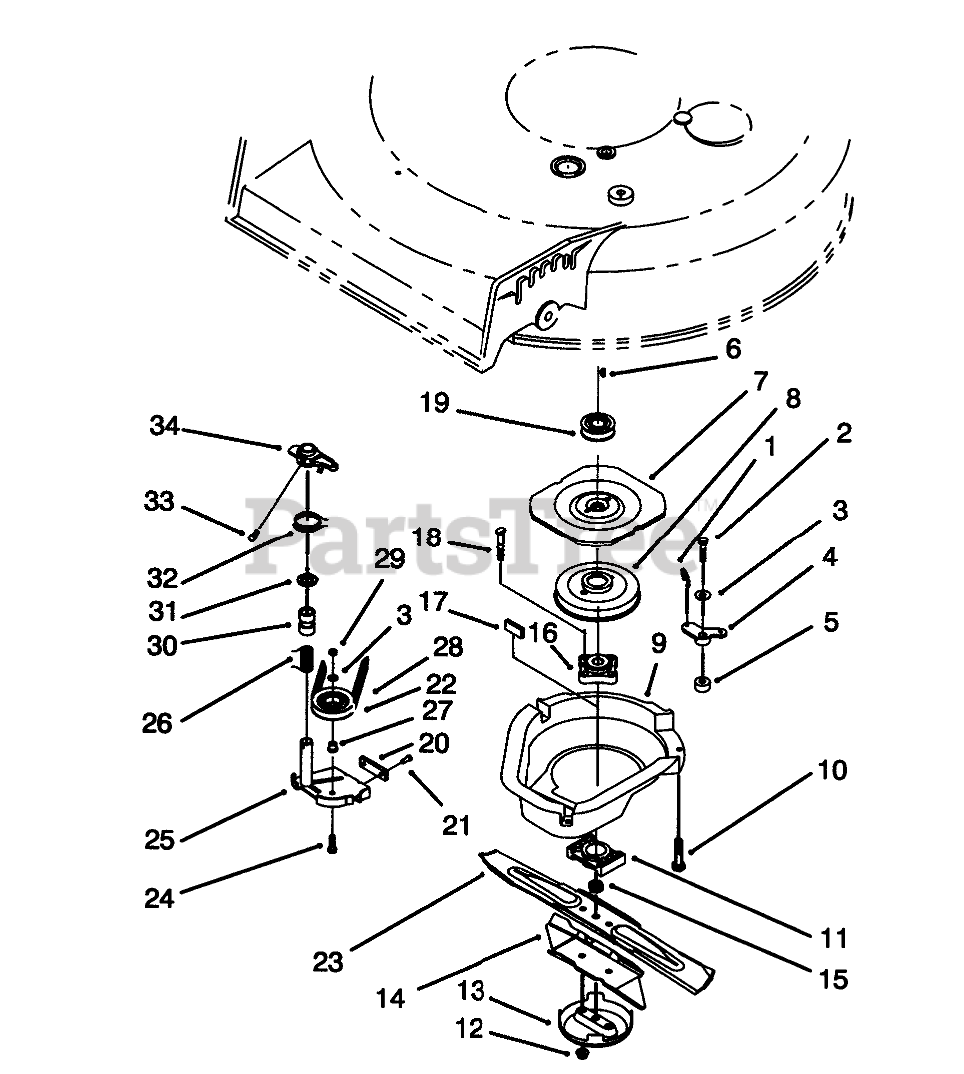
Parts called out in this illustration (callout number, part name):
1	LINK-CONTROL
2	SCREW-HH
3	WASHER-PLAIN
4	BELLCRANK
5	SLEEVE-BELLCRANK
6	KEY-WOODRUFF
7	Flywheel
8	Drum-Brake
9	SHIELD BBC
10	SCREW-HWH
11	SPACER-BLADE
12	NUT-LOCK
13	CUP-SCALP, ANTI
14	Accelerator
15	NUT-LOCK, NI
16	HUB ASM
17	DAMPENER-VIBRATION
18	BOLT-BLADE
19	PULLEY
20	Pad-Brake
21	.185 DIA X .375 RT +
22	PULLEY-IDLER
23	Blade
24	SCREW-HH
25	Brake Plate (Incl. Ref. #20 & 21)
26	SPRING-TORSION
27	HUB-PULLEY, IDLER
28	V-BELT
29	NUT-LOCK, NI
30	BEARING
31	WASHER
32	SPRING-TORSION
33	SCREW-HH
34	LEVER
